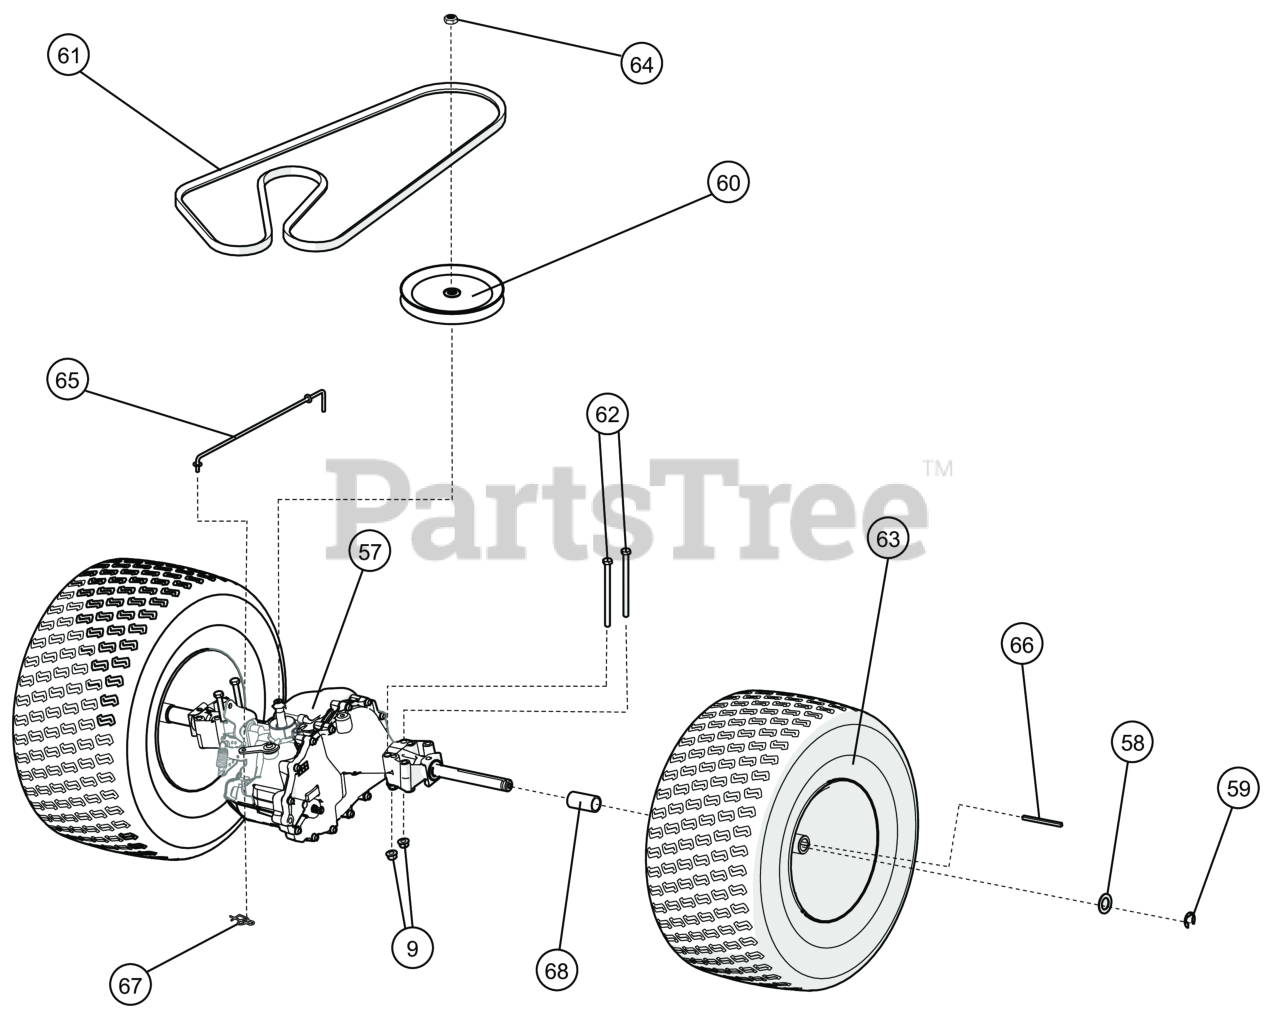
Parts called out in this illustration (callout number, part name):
9	NUT-HEX-NYLK, FLG .3125-18 ZP
57	TRANSAXLE, T2, AUGER
58	WASHER .765" ID X 1.25 OD X .06"
59	RING RETAINING "E" 3/4"
60	PULLEY, 8.00"
61	BELT, DRIVE
62	SCREWCAP 5/16 - 18X4 1/2"
63	ASM, WHEEL & TIRE, 18X9.50-8,TURF MASTER
64	NUT 1/2"-20 JAM W/LOCK
65	ROD, BYPASS, .188" X 12.00"
66	KEY 3/16" SQ X 3.00
67	1/4" RUE RING
68	SPACER REAR WHEEL
